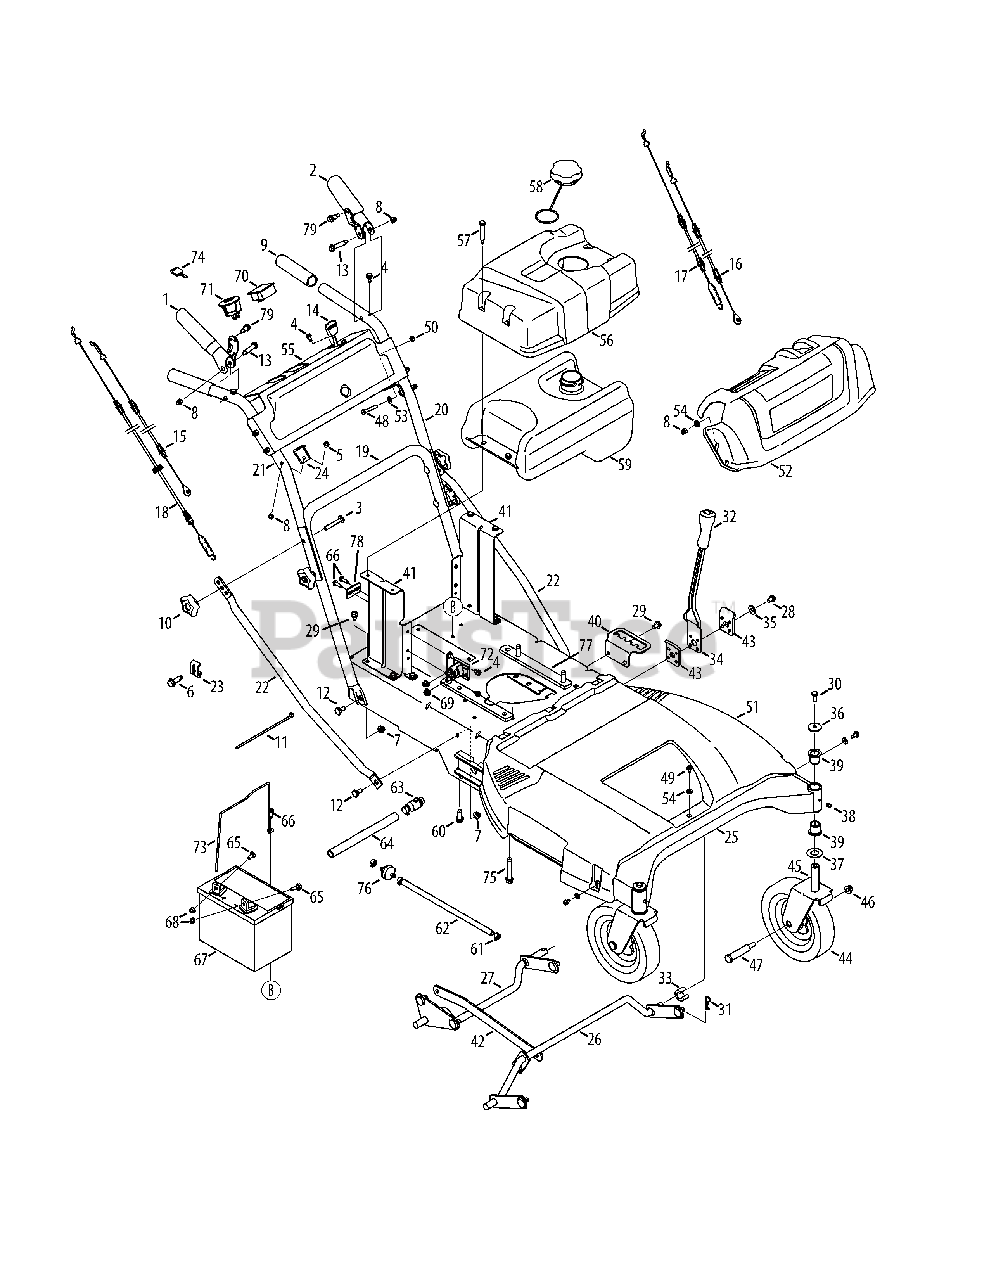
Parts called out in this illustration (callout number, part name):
1	RH Lever Assembly Bracket
2	LH Lever Assembly Bracket
3	Screw, Carriage, 5/16-18 x 2.25
4	Screw, 1/4-20 x 0.500
5	Hex Screw, 1/4-20 x 1.50
6	Screw, #10-32 x 0.625
7	Nut, Flangelock, 5/16-18
8	Lock Nut Cap, 1/4-20
9	Grip, 1.0 ID x 5.0 LG
10	Star Knob, 5/16-18
11	Cable Tie, 3/16 x .05 x 7.4
12	Screw, Shoulder, .435 x .178-5/16 x .56
13	Screw, Shoulder, .375 x 1.355 x 1/4-20
14	Throttle/Choke Cable, 38.0 x 1.1 EXT
15	RH Trans Brake Cable
16	LH Trans Brake Cable
17	Wheel Clutch Cable
18	Deck Clutch Cable
20	Upper LH Handle
21	Upper RH Handle
22	Adjustable Handle Brace
23	Casing Clamp
24	RH Cable Mount Bracket
24	LH Cable Mount Bracket
26	Front Deck Lift Assembly
27	Rear Deck Lift Assembly
28	Hex Screw, 5/16-18 x .50
29	Screw, 5/16-18 x 0.625
30	Hex Screw, 5/16-24 x .750
31	Click Pin, .092 x 1.64 LG
32	Grip Handle, 1/2
33	Plastic Spacer, .63 ID x .75 LG
34	Deck Height Lever
35	Washer, Bell, .340 x .872 x .060
36	Washer, Flat, .330 x 1.25 x .120
37	Washer, Flat, .760 ID x 1.50 OD
38	Drive Lube Fitting, 3/16
39	Flange Bearing, .760 x .941 x 1.0
40	Height Adjustment Bracket
41	Fuel Tank Mount Bracket
42	Link Pivot Bracket
43	Lever Pivot Bracket
44	Caster, Wheel, 8 x 1.75
44	Bearing, Flange w/ftg
45	Wheel Caster Bracket
46	Nut, Flangelock, 3/8-16
47	Bolt, Shoulder, .625 x 2.515 x 3/8-16
48	Hex Screw, 1/4-20 x 1.75
49	Screw, 1/4-14 x 0.625
50	Nut, Hex, 1/4-20
51	Belt Cover
52	Handle Panel, Black
53	Washer, Bell, .265 x .75 x .062
54	Washer, Flat, .25 x .630 x .0515
55	Hour Meter and Key Handle Panel
56	Fuel Tank Cover
57	Screw, Shoulder, 1/4-20 x .32 x 1.8
59	Fuel Tank
60	Screw, 3/8-16 x 1.250
61	Hose Clamp, .490 DIA.
62	Fuel Hose, Low Permeation, 1/4
64	Extension Hose
65	Hex Head Flange, 1/4-20 x .75
66	Screw, 1/4-20 x 0.750
67	Battery, 155 CCA WET
68	Sems Nut, 1/4-20
69	Nut, Flangelock, 1/4-20
70	Hour Meter
71	Key Switch
72	Solenoid, 12V, 100 AMP
73	Battery Hold Down Strap
74	Key, Yellow
75	Screw, 3/8-16 x 2.25
76	Fuel Filter
77	Engine Mounting Plate
78	PLate, Shift
79	Screw, Shoulder, 1/4-28 x .342 x .335
